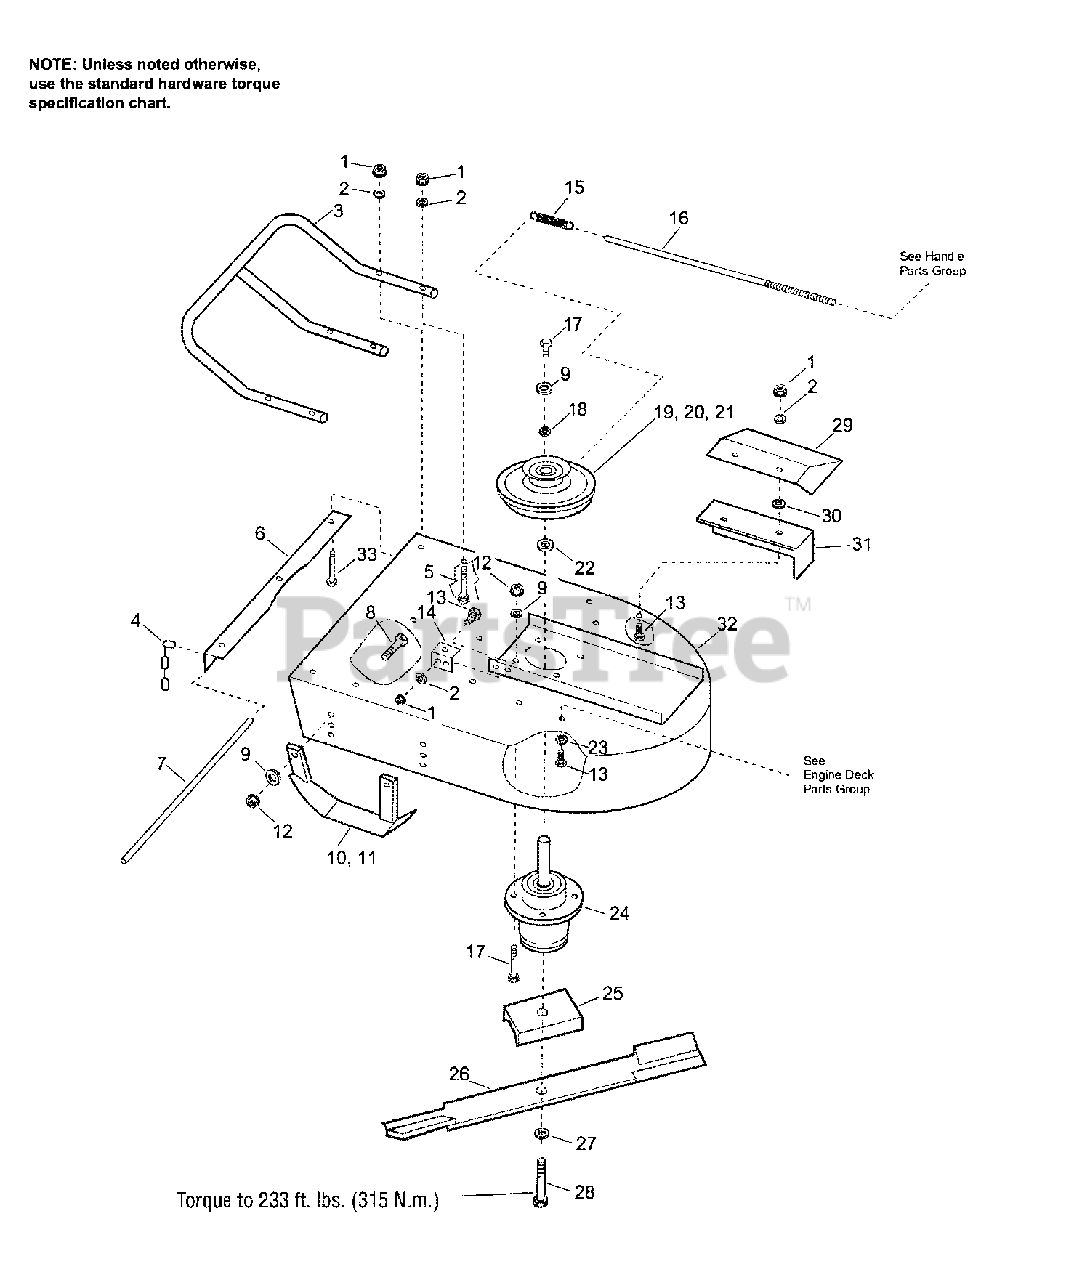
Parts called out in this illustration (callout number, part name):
1	NUT, 5/16-18 Hex, GR 5 or B
2	WASHER, 5/16" Split Lock
3	WELDMENT, Front Bumper
4	CHAIN CURTAIN
5	SCREW, 5/16-18 x 1-1/2" Hex Head Cap, GR 5
6	BRACKET, Chain Curtain
7	ROD, Chain Curtain Mounting
8	SCREW, 3/8-16 x 1 Hex Head Cap, GR 5
9	WASHER, .38 x .68 x .09 Split Lock
11	RIGHT SKID, Blade Deck (weldment)
12	NUT, 3/8-16 Hex, GR 5 or B
13	SCREW, 5/16-18 x 3/4" Hex Head Cap, GR 5
14	BRACKET, Anti-Torque
15	SPRING, Clutch
16	ROD, Blade Clutch Engagement (5/16-18 threaded)
17	SCREW, 3/8-16 x 1-1/2" Hex Head Cap, GR 5
18	WASHER, 7/16 I.D. x 1-1/2" Flat (Heavy Duty)
19	ASSEMBLY, Clutch Brake
20	SCREW, 5/16-18 x 1" Hex Head Cap
21	NUT, 5/16-18 Hex Center Lock
22	SPACER, Clutch
23	WASHER, 3/8" SAE Flat
24	ASSEMBLY, Blade Spindle
25	CHANNEL, Cutting Blade Reinforcement
26	CUTTING BLADE
27	WASHER, 5/8" Split Lock
28	CAPSCREW, 5/8-11 x 1-1/2" Socket
29	DELFECTOR, Discharge (weldment)
30	WASHER, 5/16" SAE Flat
31	COVER, Discharge (weldment)
32	BLADE DECK
33	SCREW, 5/16-18 x 1-3/4 Hex Head Cap, GR 5
